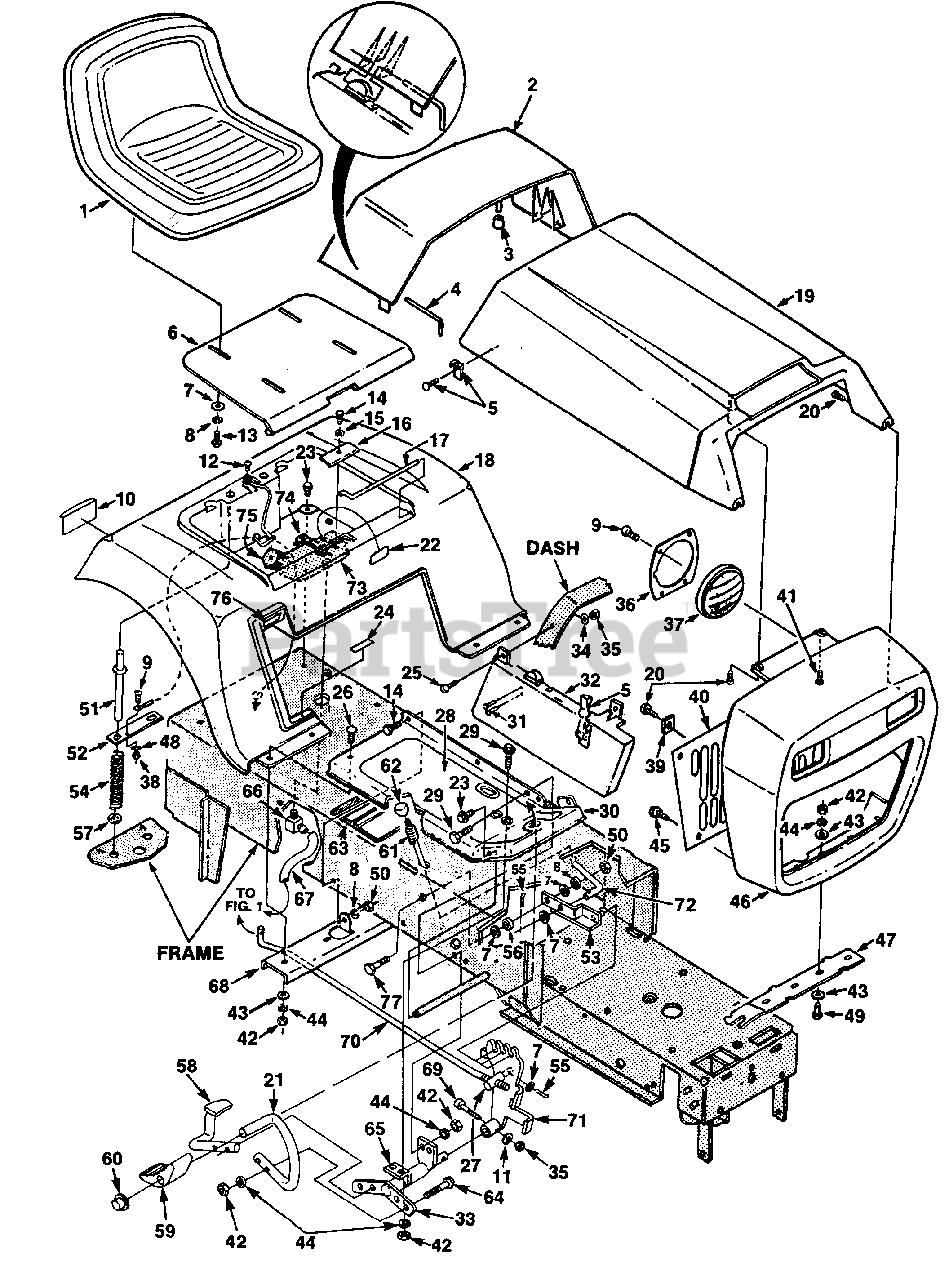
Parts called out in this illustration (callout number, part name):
2	PANEL- Hood
3	BUMPER- Rubber
4	PIN- Attachment
6	PAN- Seat
7	WASHER- Flat (5/16")
8	WASHER- Lock 5/16 Hvy.
9	SCREW- (10-24 x 3/8")
10	REFLECTOR
11	WASHER- Thrust
12	SCREW- (#10 x 1/2")
13	SCREW- (5/16-18 x 5/8")
14	SCREW- (1/4-20 x 3/4")
15	WASHER- Lock (1/4")
16	BRACKET- Rod. Ret.
17	ROD- Hinge
20	SCREW- (1/4-14 x 1") (YT-15)
21	FORWARD ARM
22	DECAL- Fill Level
24	DECAL- Lo-Lift Position
25	SCREW- (10-24 x 1/2")
26	BOLT- (1/4-20 x 1")
28	PAD- Footboard (L.H.)
29	SCREW- (1/4-20 x 5/8")
30	FOOTBOARD (L.H.)
32	PANEL- L.H. Side
33	PLATE & SHAFT
34	WASHER- Flat (#10)
35	NUT (#10-24)
36	RETAINER- Headlight
37	HEADLIGHT
38	NUT- (10-24)
39	CLIP- Grill Top
41	SCREW- (1/4-14 x 3/4") (YT-15)
42	NUT- Hex (1/4-20)
43	WASHER- Plain (1/4") (YT-15)
44	WASHER- Lock (1/4")
45	SCREW- (1/4-14 x 1/2")
47	GRILLE HINGE
48	LOCKWASHER (#10)
49	SCREW- (1/4-20 x 7/8")
50	NUT- Hex (5/16-18)
51	PIN- Seat Support
52	CONTACT- Interlock
53	CONTROL ARM
54	SPRING- Compression
55	PIN- Cotter (3/32 x 3/4")
57	WASHER- Insulating
58	ARM- Reverse
59	PEDAL- Rubber
60	NUT- (5/8")
63	DECAL- Operation Warning
64	SCREW- (1/4-20 x 1/2")
65	TUBE & SUPPORT
66	CONNECTOR
67	TUBING- Reservoir (7.25)
68	BRACKET- Footboard
69	SCREW- Socket (#10-24 x 1/3/4")
72	ROD- Cruise Control
73	RESERVOIR
76	DECAL- High Lift Position
77	SCREW- Hex Hd. Cap (5/16-18 x 1 1/4")
